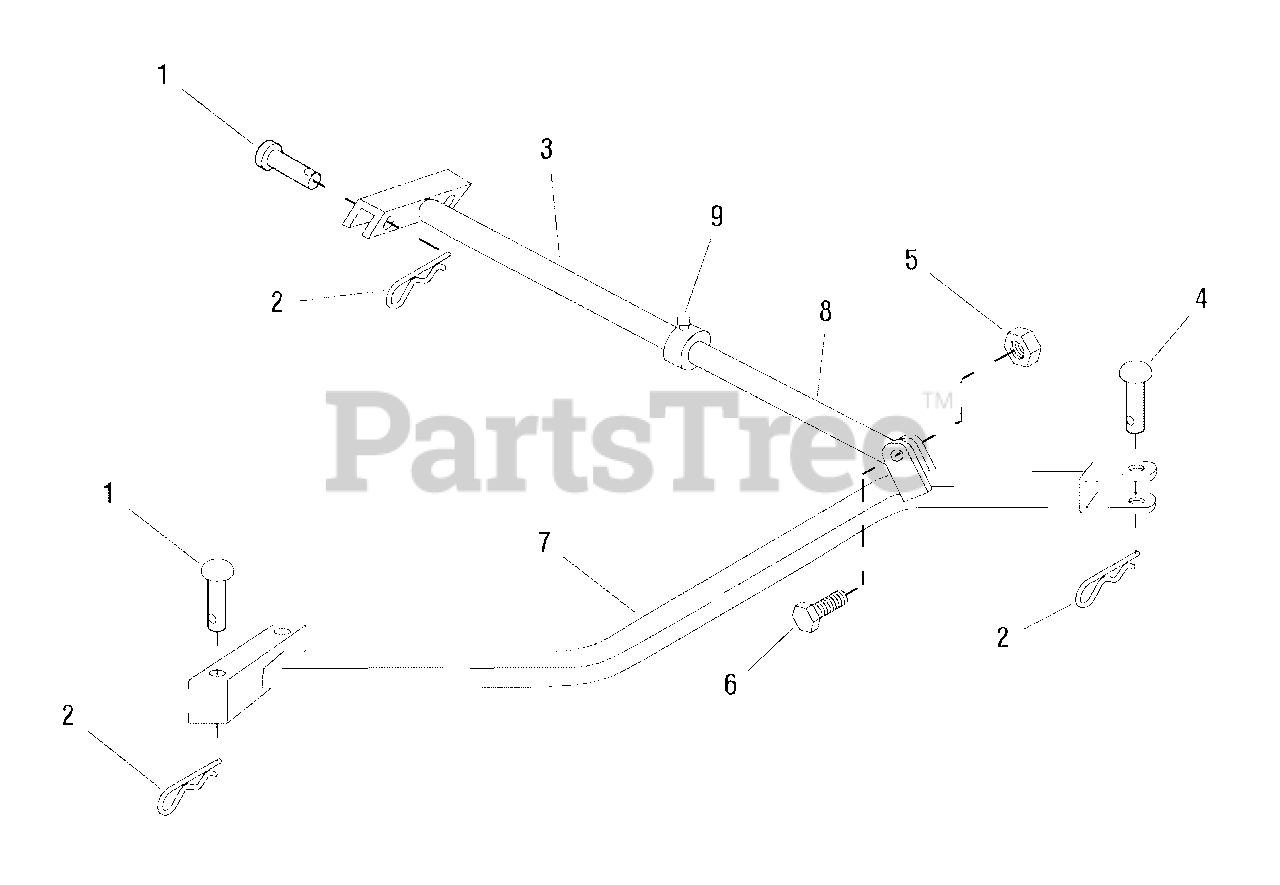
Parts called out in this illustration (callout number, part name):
2	PIN, Quick, 3/32 x 1-7/8
3	SWING ARM ASSEMBLY
4	PIN, 3/8 x 2
5	NUT, Hex Lock, 5/16 - 18
6	CAPSCREW, Hex, 5/16 - 18 x 2
7	TOW BAR
8	ROD
9	SET SCREW, 5/16 - 18 x 5/8
